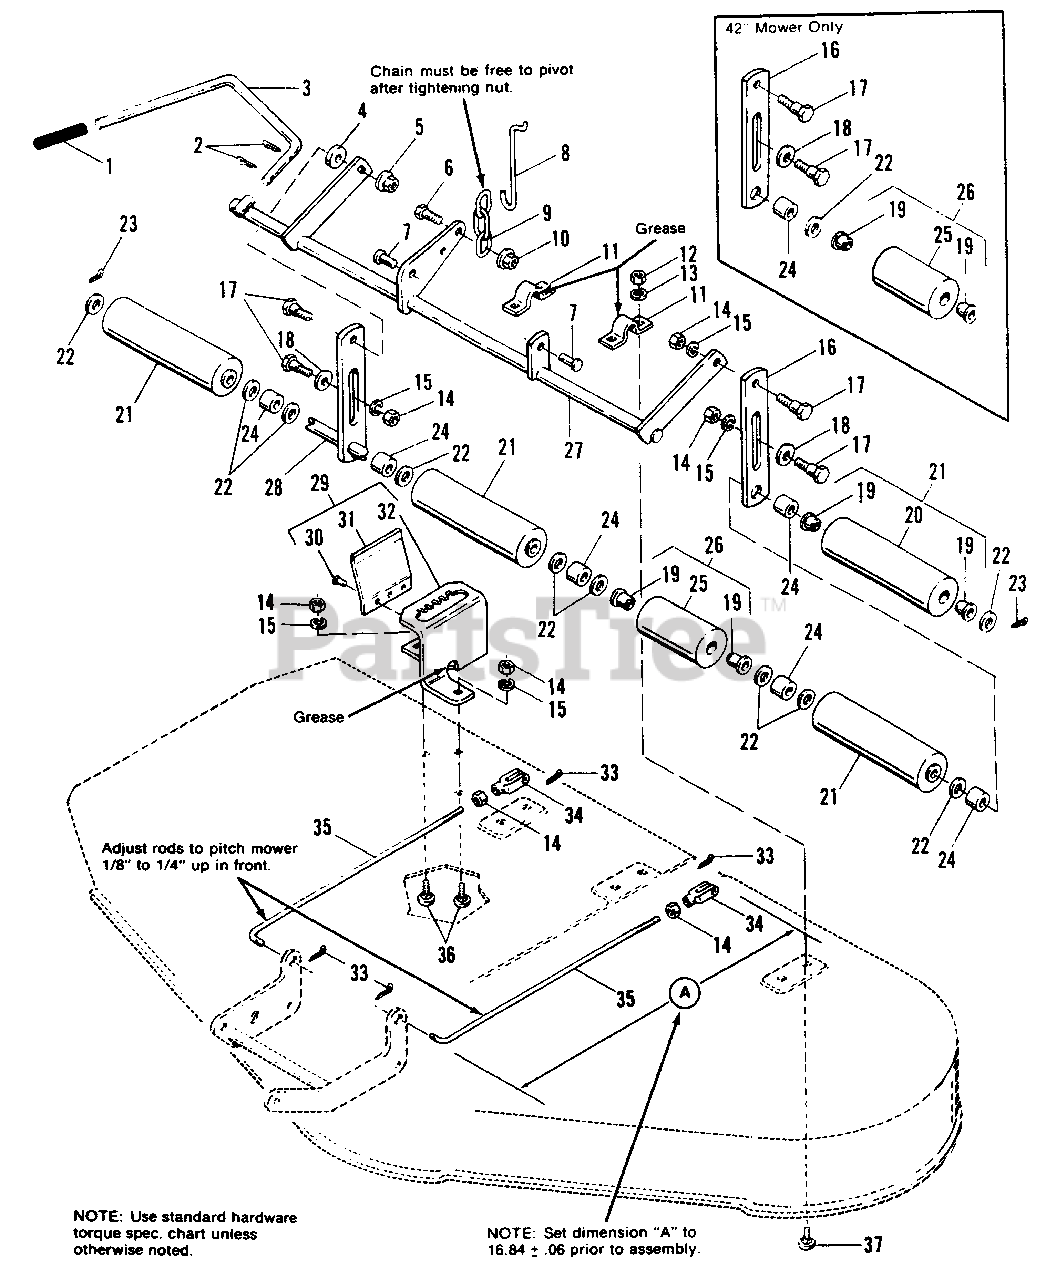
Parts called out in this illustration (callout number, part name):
2	PIN, Cotter, 1/8 x 1
3	LEVER, Control
4	WASHER, Plain, 13/32
5	LOCKNUT, Hex, Flange, Whiz, 3/8-16
6	CAPSCREW, Hex, 5/16-18 x 1
7	PIN, Clevis
9	LIFT, Chain
10	LOCKNUT, Flange, 5/16-18
11	STRAP
12	NUT, Hex, 5/16-18
13	LOCKWASHER, 5/16
14	NUT, Hex, 3/8-16
15	LOCKWASHER, 3/8
16	BAR, Roller
17	BOLT, Shoulder, 3/8-16 X 1.34
18	WASHER, Plain, 7/16
21	ROLLER ASSY, Large (Qty. 3 on 42" Mower only)
22	WASHER, 25/32 x 1-1/4
23	PIN, Cotter, 3/16 x 1
24	SPACER, .66 ID
26	ROLLER ASSY., Small (Qty. 1 on 48" Mower only)
27	ARM ASSY, Mower
28	SHAFT ASSY., Roller (48" Mower only)
28	SHAFT ASSY., Roller (42" Mower only)
29	QUADRANT ASSY.
33	PIN, Cotter, 3/32 x 3/4
34	CLEVIS, Adj.
36	BOLT, Carriage 3/8-16 x 3/4
37	BOLT, Carriage 5/16-18 x 3/4
